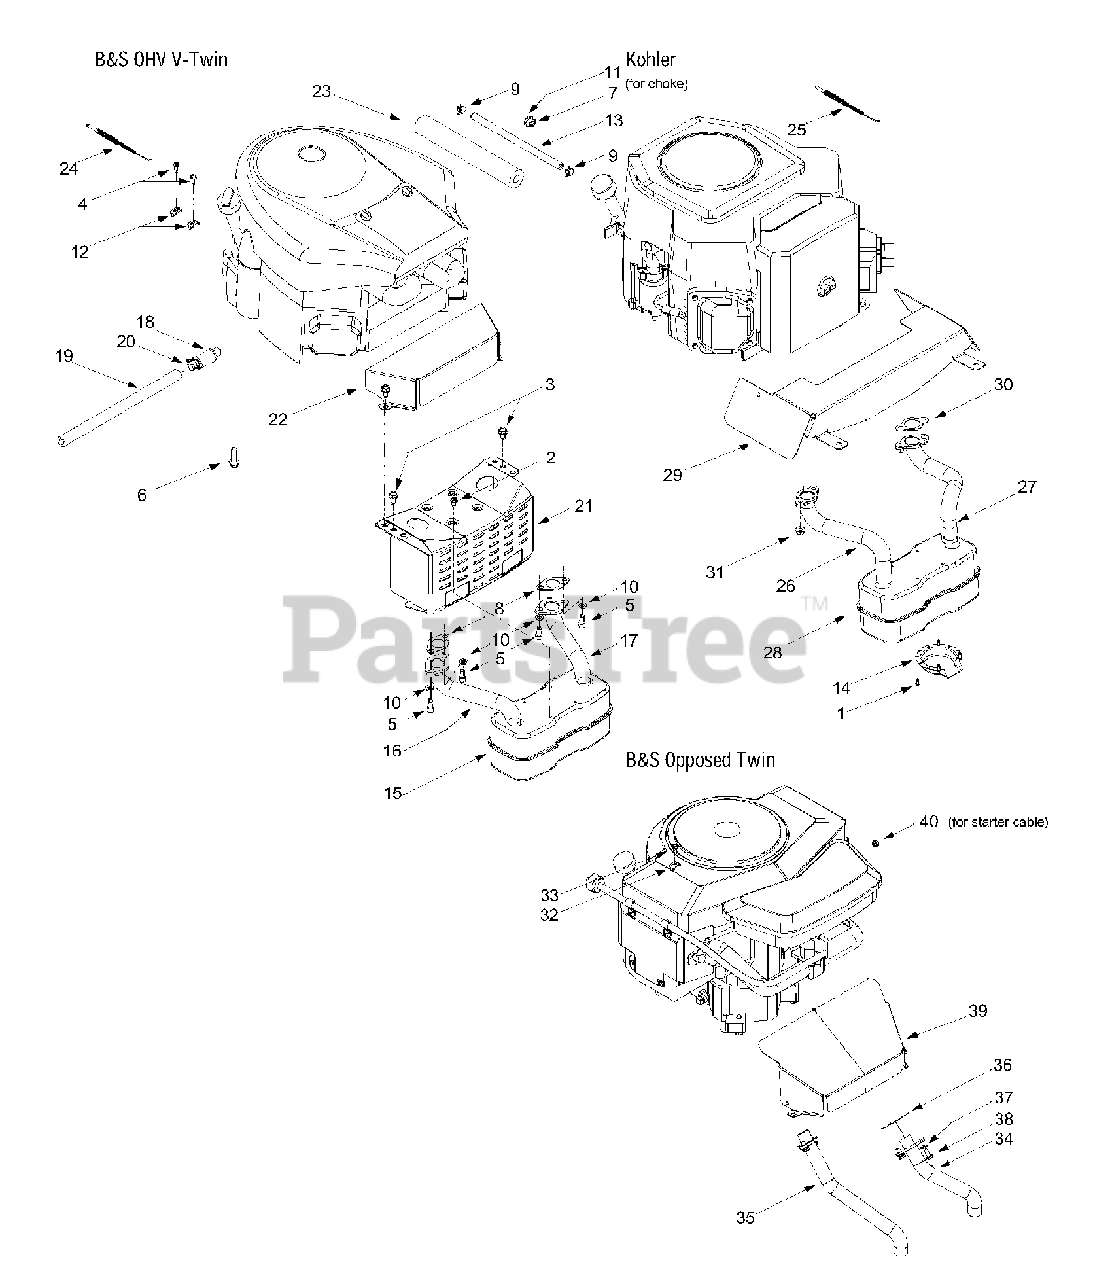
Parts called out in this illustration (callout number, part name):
1	Self-tapping Screw, #8-18 x .5
2	Self-tapping Screw, 1/4-20 x .5
3	Self-tapping Screw, 5/16-18 x .625
4	Screw, #10-32 x .625 (B&S OHV V-Twin)
5	Socket Cap Screw, 5/16-18 x .625
6	Self-tapping Screw, 3/8-16 x 1.25
7	Hex Nut, 3/8-16
8	Exhaust Gasket (B&S OHV V-Twin)
9	Hose Clamp
10	Lock Washer, 5/16
11	Flat Washer
12	Casing Clamp (B&S OHV V-Twin)
13	Fuel Line Hose
14	Muffler Deflector
15	Muffler, Twin Inlet (B&S OHV V-Twin & Opposed Twin)
16	RH Exhaust Pipe (B&S OHV V-Twin)
17	LH Exhaust Pipe (B&S OHV V-Twin)
18	Oil Drain Valve
19	Oil Drain Hose
20	Oil Drain Cap
22	Engine Heat Shield (B&S OHV V-Twin)
23	Foam (fits over fuel line)
24	Throttle Cable (B&S OHV V-Twin & Opposed Twin)
25	Throttle Cable (Kohler)
26	RH Exhaust Pipe (Kohler)
27	LH Exhaust Pipe (Kohler)
28	Muffler, Twin Inlet (Kohler)
29	Engine Heat Shield (Kohler)
30	Exhaust Gasket (Kohler)
31	Flange Nut, M8 x 1.25-6 (Kohler)
32	Clamp, 9/16 (B&S Opposed Twin)
33	Screw, #10-16 x .5 (B&S Opposed Twin)
34	LH Exhaust Pipe (B&S Opposed Twin)
35	RH Exhaust Pipe (B&S Opposed Twin)
36	Exhaust Gasket (B&S Opposed Twin)
37	Lock Washer, 1/4 (B&S Opposed Twin)
38	Hex Screw, 1/4-20 x .620 (B&S Opposed Twin)
40	Hex Sems Nut, 1/4-20 (B&S Opposed Twin)
